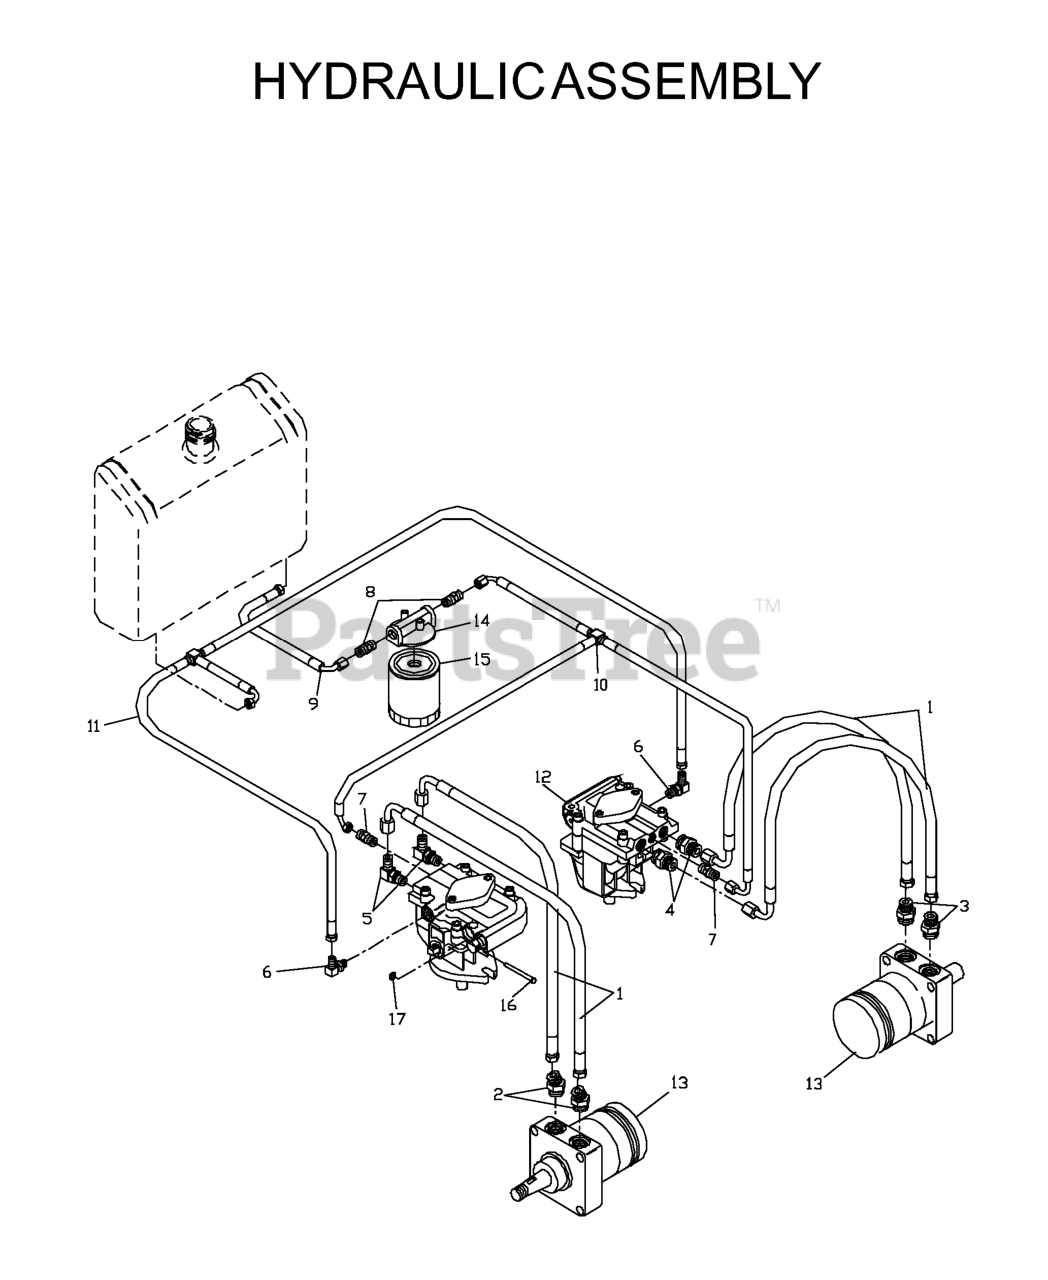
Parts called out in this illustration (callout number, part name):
1	HOSE, 1/2" HYDRAULIC
2	ELBOW-ADJ 45 DEG F6802-8-10
3	CONNECTOR, STRAIGHT
4	FITTING, STRAIGHT F6400-8-8-0
5	ELBOW, 90 DEGREE
6	ELBOW, F6801-6-6-0 90 DEGREE
7	FITTING, STRAIGHT F6400-6-4-0
8	STRAIGHT FITG
9	HOSE
10	INLET TEE HOSE
11	RETURN TEE HOSE
13	WHEEL MOTOR
14	FILTER HEAD
15	HYDRAULIC OIL FILTER
16	CLEVIS PIN
